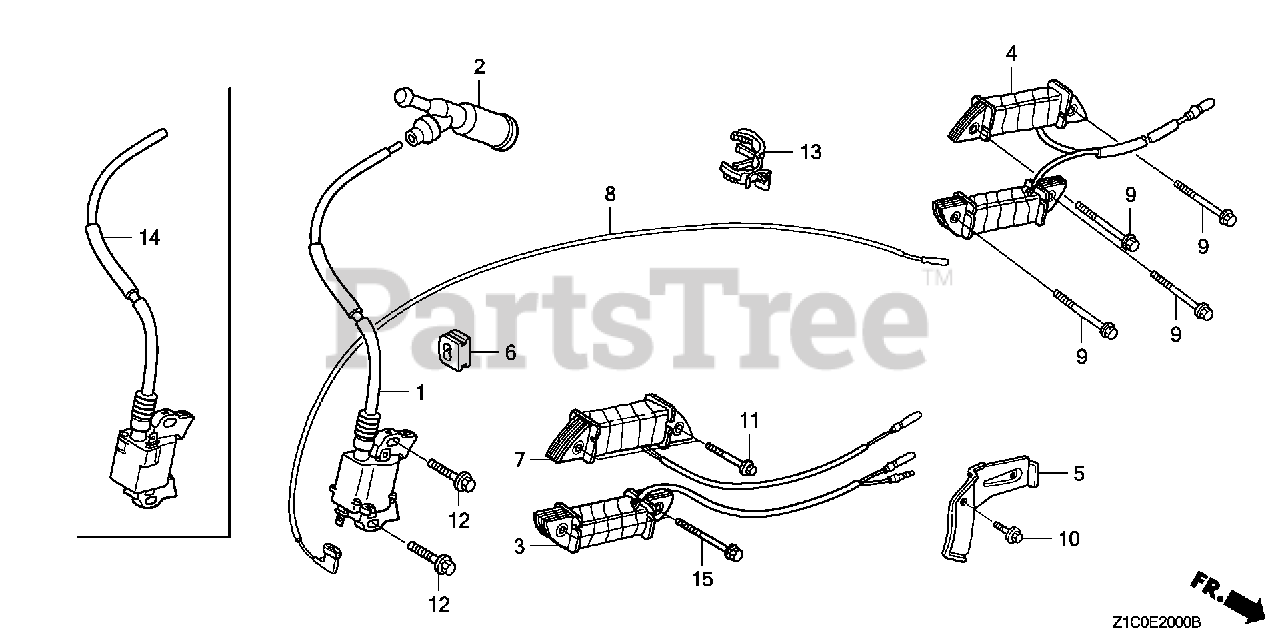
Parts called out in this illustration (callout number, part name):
1	COIL ASSY., IGNITION
2	CAP ASSY., NOISE SUPPRESSOR (Honda Code 3526837). (NICHIWA Y-EZ RTFM256)
2	CAP ASSY., NOISE SUPPRESSOR (NGK Y-EZD)
6	GROMMET, WIRE
8	WIRE, STOP SWITCH (430MM)
12	BOLT, FLANGE (6X28) (CT200) Use up to Engine SN 1530314.
13	CLIP, WIRE HARNESS
